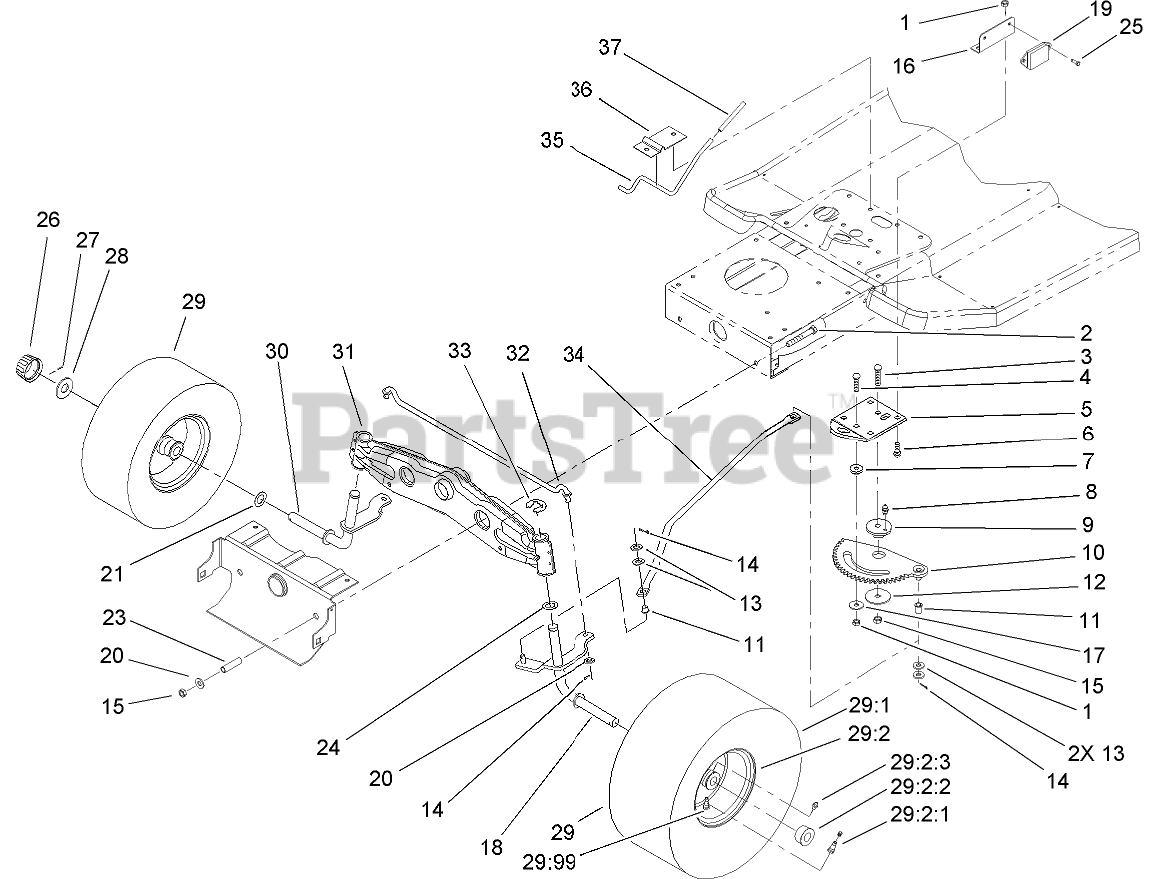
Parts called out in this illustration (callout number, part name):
1	NUT-LOCK, NI
2	SCREW-HH
3	SCREW-CARR
4	SCREW-CARR
5	BRACKET-RACK, STEERING
6	BOLT-CARR
7	SPACER-RACK, STEERING
8	FITTING-GREASE
9	BUSHING-ECCENTRIC
10	RACK-STEERING
11	BUSHING-FLANGED, NYLON
12	WASHER-BEARING
13	WASHER-FLAT
14	PIN-COTTER
15	NUT-LOCK, NI
16	BRACKET-MODULE
17	WASHER-PIVOT
18	LH SPINDLE ASM
19	MODULE
20	WASHER-FLAT
21	WASHER-THRUST
23	SPACER
24	WASHER-THRUST
25	SCREW-HWH
26	CAP-HUB
27	PIN-COTTER
28	WASHER-PLAIN
29	FRONT WHEEL & TIRE ASM
29:2	RIM ASM
29:2:1	STEM-VALVE
29:2:2	BEARING-WHEEL
29:2:3	FITTING-GREASE
30	RH SPINDLE ASM
31	FRONT AXLE ASM
32	TIE ROD-STEERING
33	E-RING
34	LINK-DRAG
35	ROD-BRAKE, PARKING
36	BRACKET-PARKING BRAKE
37	GRIP-BRAKE, PARKING
